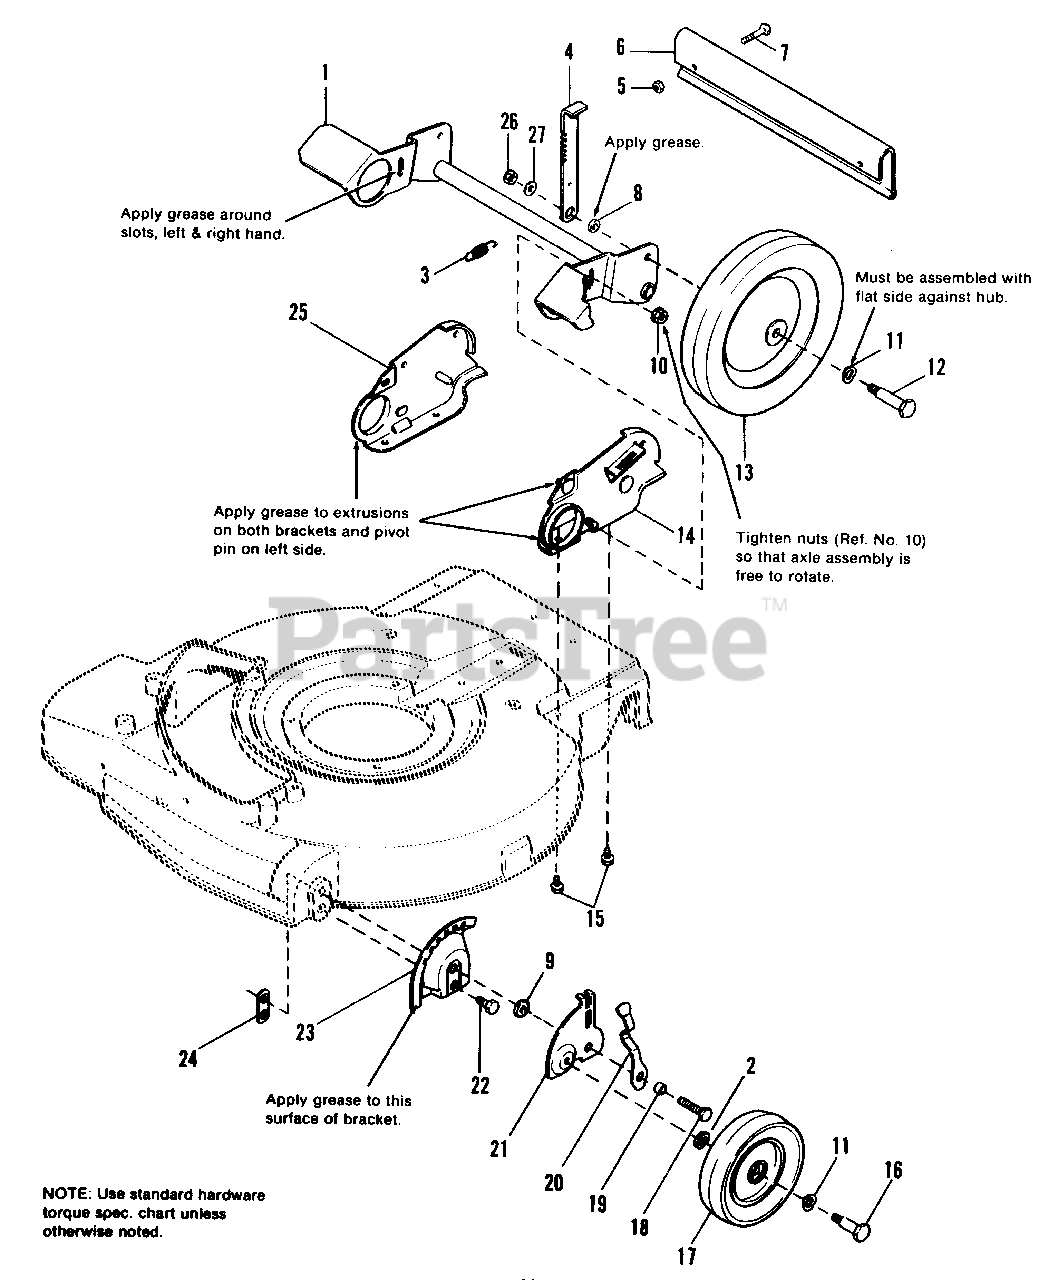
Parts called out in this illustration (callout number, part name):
1	PLATE & TUBE ASSY.
2	SPACER-Front Wheel (1691100,if required)
4	ADJUSTER, Height, Rear
5	LOCKNUT, Hex Nlyon, #10-24
6	SHIELD, Trailing, Assembly
7	CAPSCREW, Hex Hd., #10-24 x 1-1/2
9	WASHER, Std. 5/16
10	NUT, Hex, 5/16-18 Lock
11	WASHER, Special
12	BOLT, Wheel
13	WHEEL, 10" Steel
14	BRACKET ASSY., L.H.
15	SCREW, Taptite, 1/4-20 x 1/2
16	* BOLT, Front Wheel
17	WHEEL, 6" Front
18	SCREW, Special, 3/8-16 x 1-1/4
20	SPRING, Height Adjustment
21	ADJUSTER, Height, Front
22	CAPSCREW, Hex 3/8-16 x 3/4
23	PLATE, Adjuster
24	NUT, Pilot, Twin
25	BRACKET ASSY., R.H.
26	NUT-Hex 3/8-16 Jam
27	WASHER. Std 3/8
